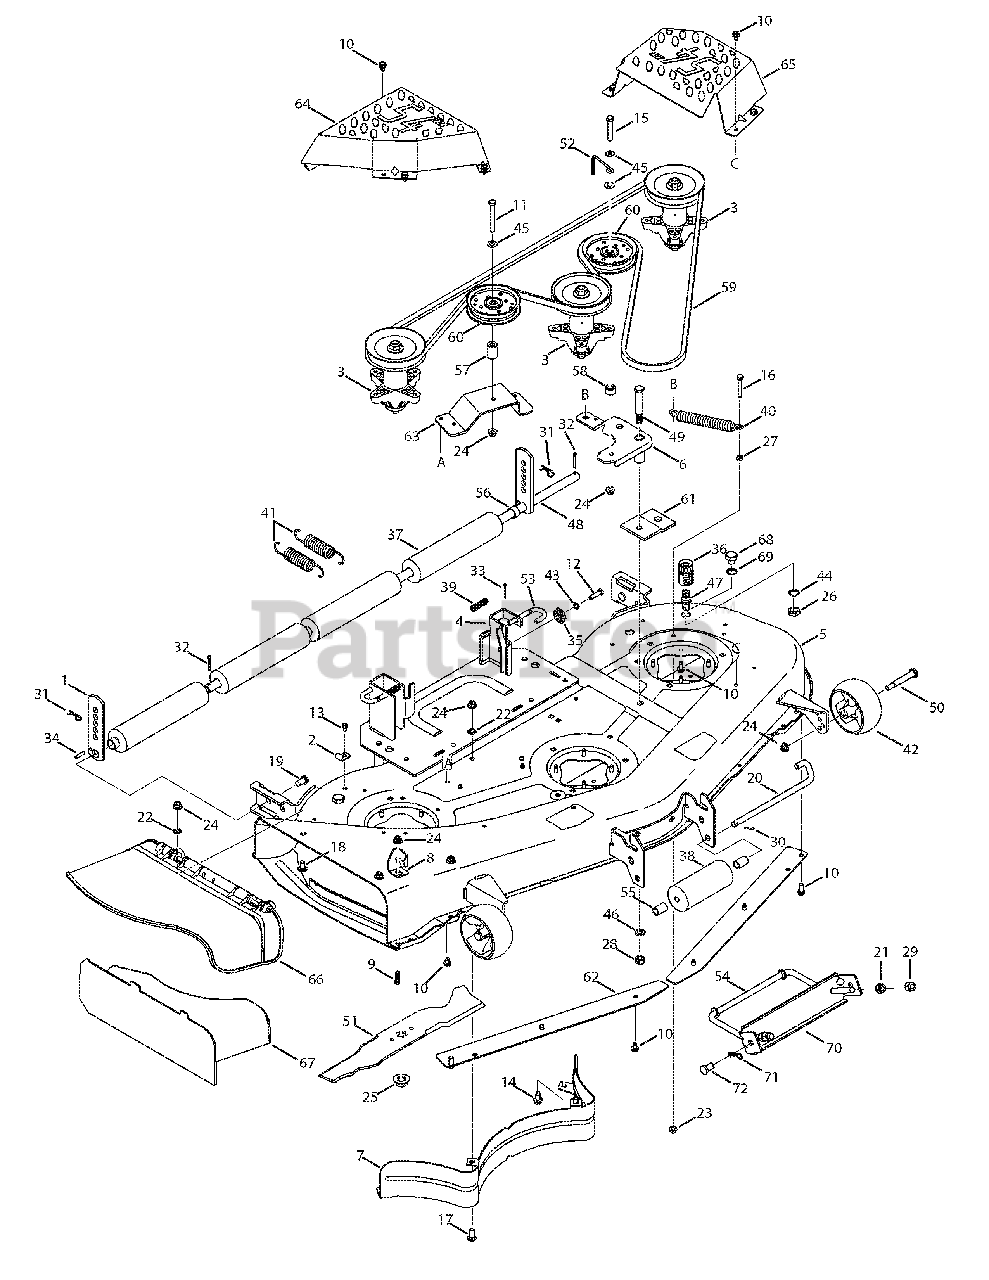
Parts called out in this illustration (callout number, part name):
1	Bracket, Adjustment, Height
2	Bracket, Hook, Retainer
3	Spindle Assembly, Pulley
4	Bracket Asbly, Deck Hanger LH
5	Deck Asmbly., 54" SD GT
6	Idler Assembly, 54" Deck
7	RR Inner Baffle
8	Deflector Chute Stop
9	Hex Screw 3/8-16 x 1.0
10	Screw, 5/16-18 x 0.750
11	Screw, 3/8-16 x 3.00
12	Hex Screw, 5/16-18 x 1.25
13	Screw, 1/4-20 x.500
14	Screw, 3/8-16 x.750
15	Screw, 3/8-16 x 2.50
16	Hex Screw, 5/16-18 x 2.00
17	Bolt, Carriage, 3/8-16 x 1.0
18	Carriage Bolt 3/8-16 x.75
19	Pin, Clevis,.50 Dia x.78
20	Pin, Roller,.5" Dia x 10.06.
21	Hex Nut, 1/2-13
22	Push Nut Retainer
23	Nut, Flange Lock, 5/16-18
24	Nut, Lock, Flange, 3/8-16
25	Nut, Hex Flange, 5/8-18
26	Hex Nut M16
27	Nut, Hex, 5/16-18, Gr5
28	Nut, Hex Lock, 1/2-13
29	Hex Lock Nut, 1/2-13
30	Pin, Cotter, 3/32 x 1.00
31	Pin, Click,.092 x 1.64
32	Cotter Pin
33	Pin, Cotter, 1/8 x 1.25
34	Pin, Spring 1/4 Dia x 1.00
35	Adjustment, Deck, Gear
36	Water Nozzle Adaptor
37	Roller, Deck
38	Front Roller
39	Spring, Compression
40	Spring, Ext., .94 Dia. x 6.74
41	Spring, Ext., 1.15 Dia. X 5.99
42	Deck Wheel, 5" Dia.
43	Lock Washer
44	Lock Washer, 5/8"
45	Washer, Flat.406 x.875 x.059
46	Lock Washer
47	Deck Wash Water Nozzle
48	Shaft,.750 x.47.12
49	Shoulder Screw
50	Shoulder Screw
51	Blade, 18.50"
52	Idler Belt Keeper Rod
53	Deck Rels. Hndl. Rod,.375 Dia
54	Rod, Deck Adjust
55	Spacer.550 ID x.755 OD x 1.1
56	Spacer,.82 ID x 1.00 OD x.53
57	Spacer,.380 x.900 x 1.313
58	Spacer,.385 ID x.88 x.64
59	Belt, V-Type, B Section
60	Pulley, Idler, 4.25 Dia.
61	Bracket, Stabilizing
62	Deck Skirt
63	Bracket, Idler
64	Cover, Spindle RH
65	Cover, Spindle LH
66	Chute Assembly
67	Mulch Plug
68	Plug, Bolt, M16 x 1.5
69	Washer, Flat, .64 x 1.24 x .06
70	Front Deck Rod Adjustment Bracket
71	Hairpin Clip
72	Clevis Pin, .50 x .78
